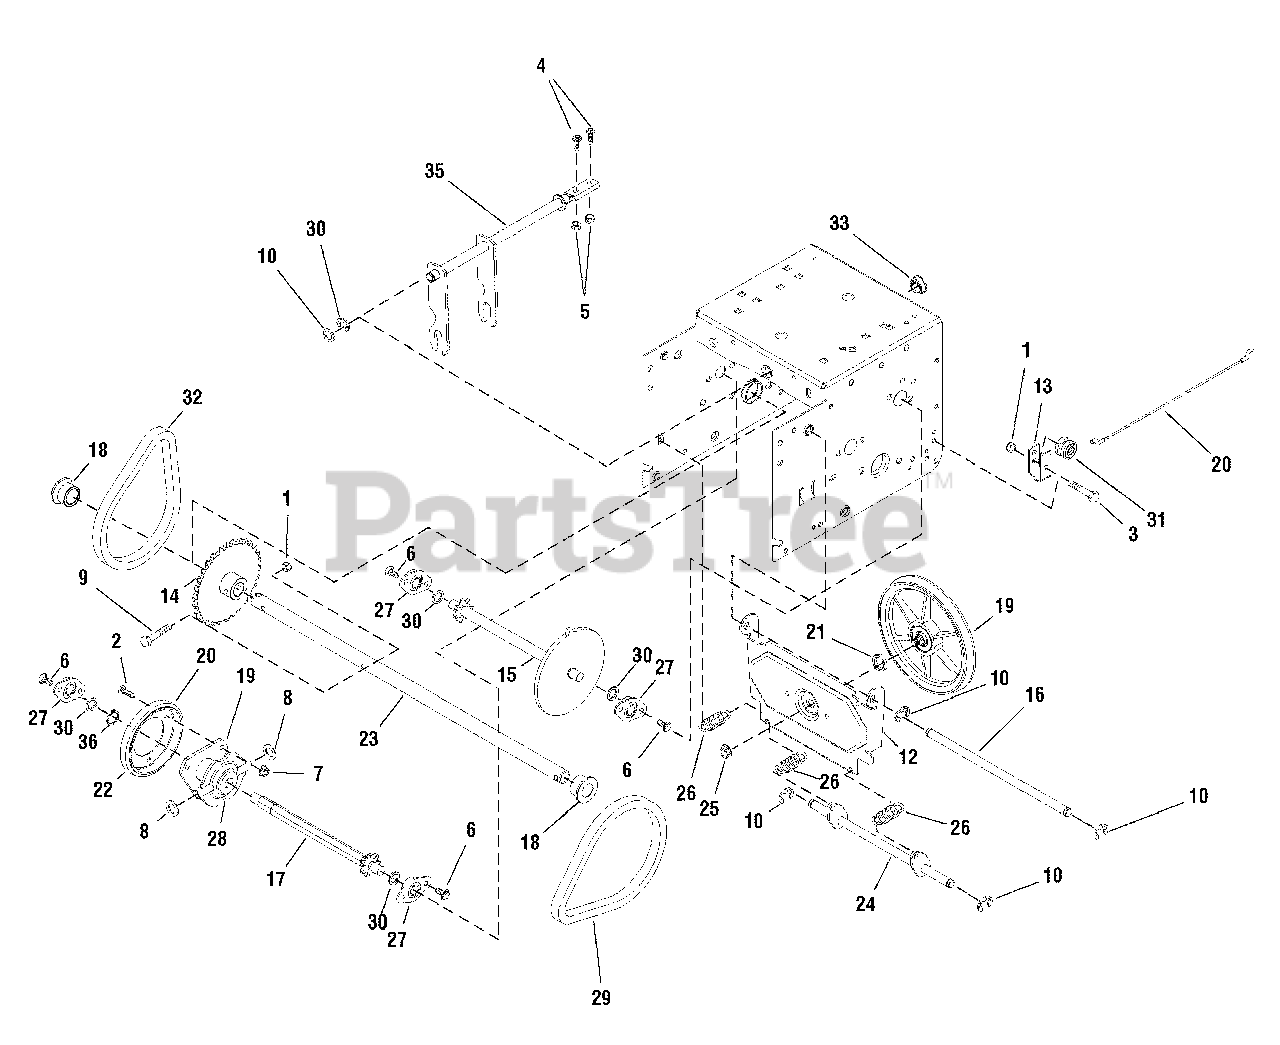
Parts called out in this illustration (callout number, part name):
1	NUT, Hex Lock Esna Light 1/4-20
2	CAPSCREW, Hex Head 1/4-20 x 5/8 G5
3	CAPSCREW, Hex Head 1/4-20 x 1-1/2 G5
4	CAPSCREW, Hex Head 1/4-20 x 3/4 G5
5	NUT, Hex Centerlock 1/4-20
6	SCREW, Hex Washer Head Taptite 5/16-18 x 1/2
7	NUT, Hex Keps 1/4-20
8	WASHER, 1/2
9	BOLT, Hex 1/4-20 x 1-3/4 G8
10	RETAINER, Ring 7/16
12	PLATE, Swinging
13	BRACKET, Cable Spool
14	WELD, Axle Sprocket
15	SPROCKET, Set
16	AXLE, Swing Plate
17	HEX SHAFT & SPROCKET ASSEMBLY
18	BEARING, Axle D-Hole
19	FRICTION PULLEY ASSEMBLY
20	CABLE, Front Drive
21	SPACER, Friction Pulley
22	WHEEL, Friction
23	AXLE
24	WELD, Spring Link
25	NUT, 38-24 FlangeLock
26	SPRING, Extension
27	RETAINER & BUSHING ASSEMBLY
28	HUB, Friction Wheel & Bearing
29	CHAIN, Roller
30	WASHER, Flat
31	SPOOL CABLE, Auger Control
32	CHAIN, Roller
33	BEARING, Flange 1/2 x 7/8
35	WELD, Speed Select
36	RING, Retaining Extension
